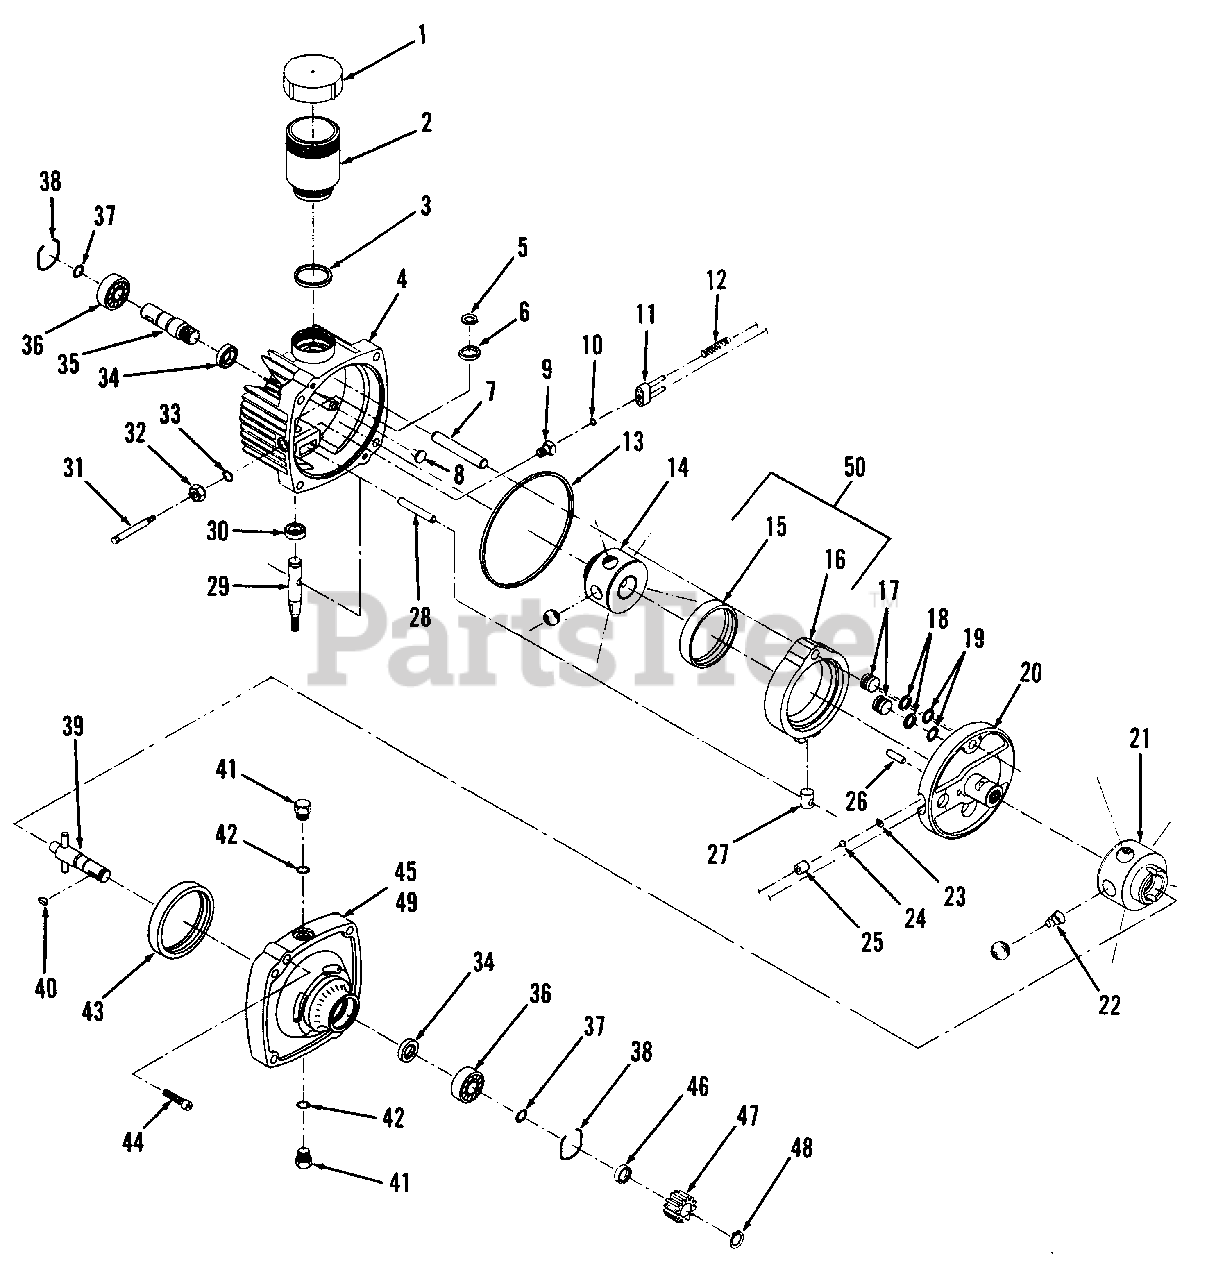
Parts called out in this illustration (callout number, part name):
1	RESERVOIR COVER, Sub-Assy.
2	RESERVOIR BODY
3	SEAL RING, Square Cut
4	COVER, Service Kit (Includes Ref. Nos. 5, 6, 7, 28, 29, 30 & 34)
5	RING, External Retaining
6	WASHER, Control Shaft
9	FITTING GUIDE, O-Ring, S.A.
10	O-RING
11	BRACKET, Pins, Sub-Assy.
12	SPRING, Valve
13	SEAL RING, Square Cut
14	PUMP ROTOR, Ball, Sub-Assy.
20	PINTLE, Sub-Assy. (Includes Ref. Nos. 17, 18, 19, 23, 24, 25 & 26)
21	MOTOR ROTOR, Ball, Sub-Assy. (Includes Qty. 5 of Ref. No. 22)
22	SPRING, Piston
27	CAM RING, Insert
31	SHAFT, Dump Valve
32	NUT, Gasket, Sub-Assy.
33	O-RING
34	SEAL, Oil
35	SHAFT, Input
36	BEARING, Ball (Input)
38	RING, Retaining
39	OUTPUT SHAFT, Sub-Assy.
40	* KEY, Woodruff
41	O-RING, Sub-Assy.
42	TUBE FITTING, O-Ring
44	CAPSCREW, Socket Hd.
48	RING, External Retaining
49	BODY, Sub-Assy. (Includes Ref. Nos. 34, 36, 37, 38, 39, 43 & 45)
50	CAM RING, Sub-Assy. (Includes Ref. Nos. 15 & 16)
